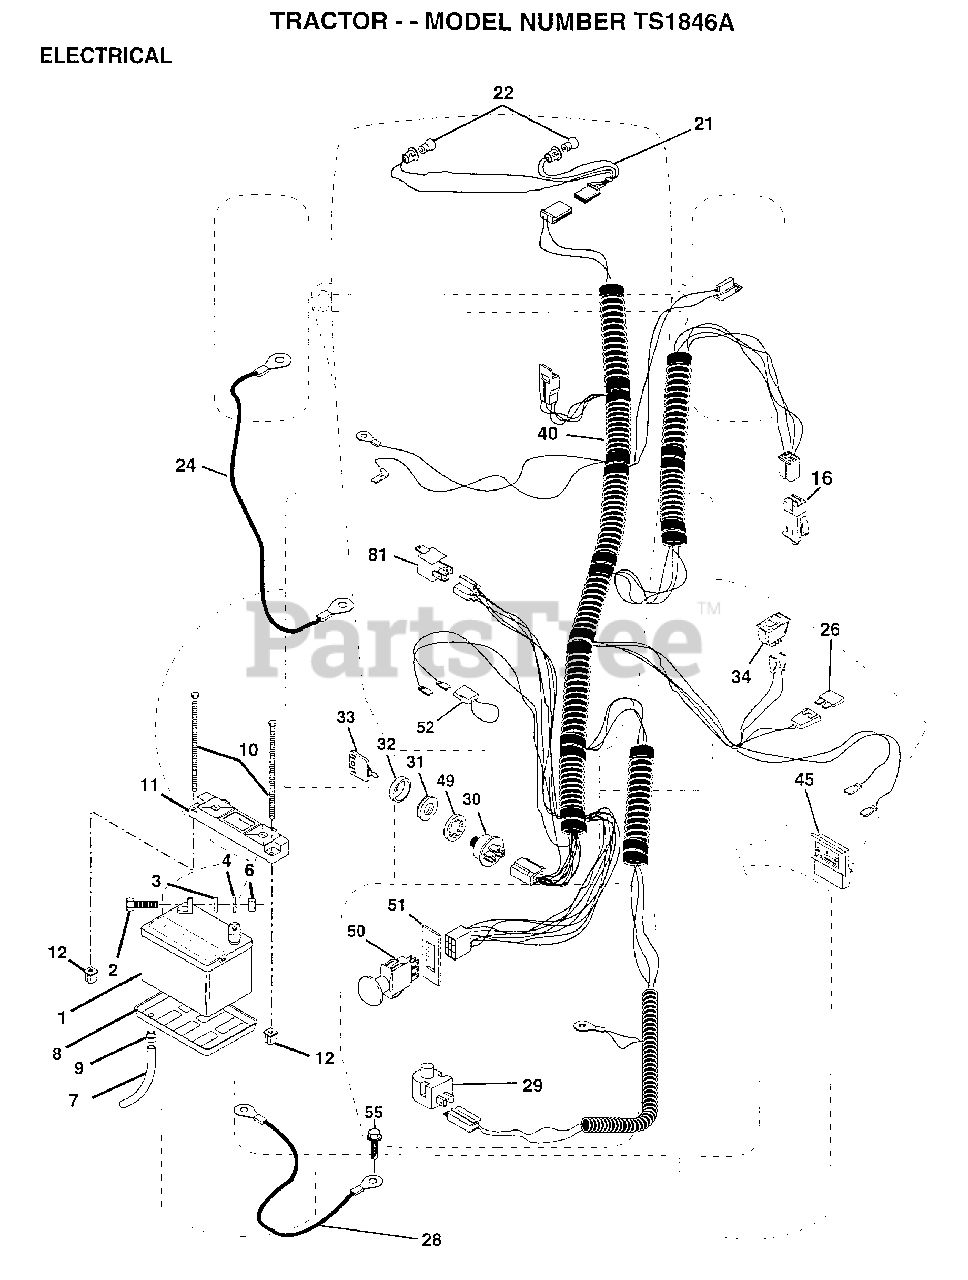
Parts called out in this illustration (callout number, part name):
2	BOLT LT
3	WASHER
4	LOCKWASHER
7	"DRAIN TU T, BATT"
8	"TRAY T, BATTERY"
9	HOSE CLAMP T
16	SWITCH INTERLOCK
21	"HARNESS,LIGHT SOC"
22	HEADLAMP BULB
24	CABLE.BATTERY.RED
26	FUSE HYT
28	CABLE.GRND.6GA.21
29	SWITCH SEAT
30	SWITCH T
31	NUT IGNITION
33	KEY
34	SWITCH LT
40	HARNESS IGNITION
45	AMMETER
49	LOCKWASHER
51	RING RETAIN PTO
52	PROTECTION LOOP
55	SCREW LT
81	RELAY ASSY T
